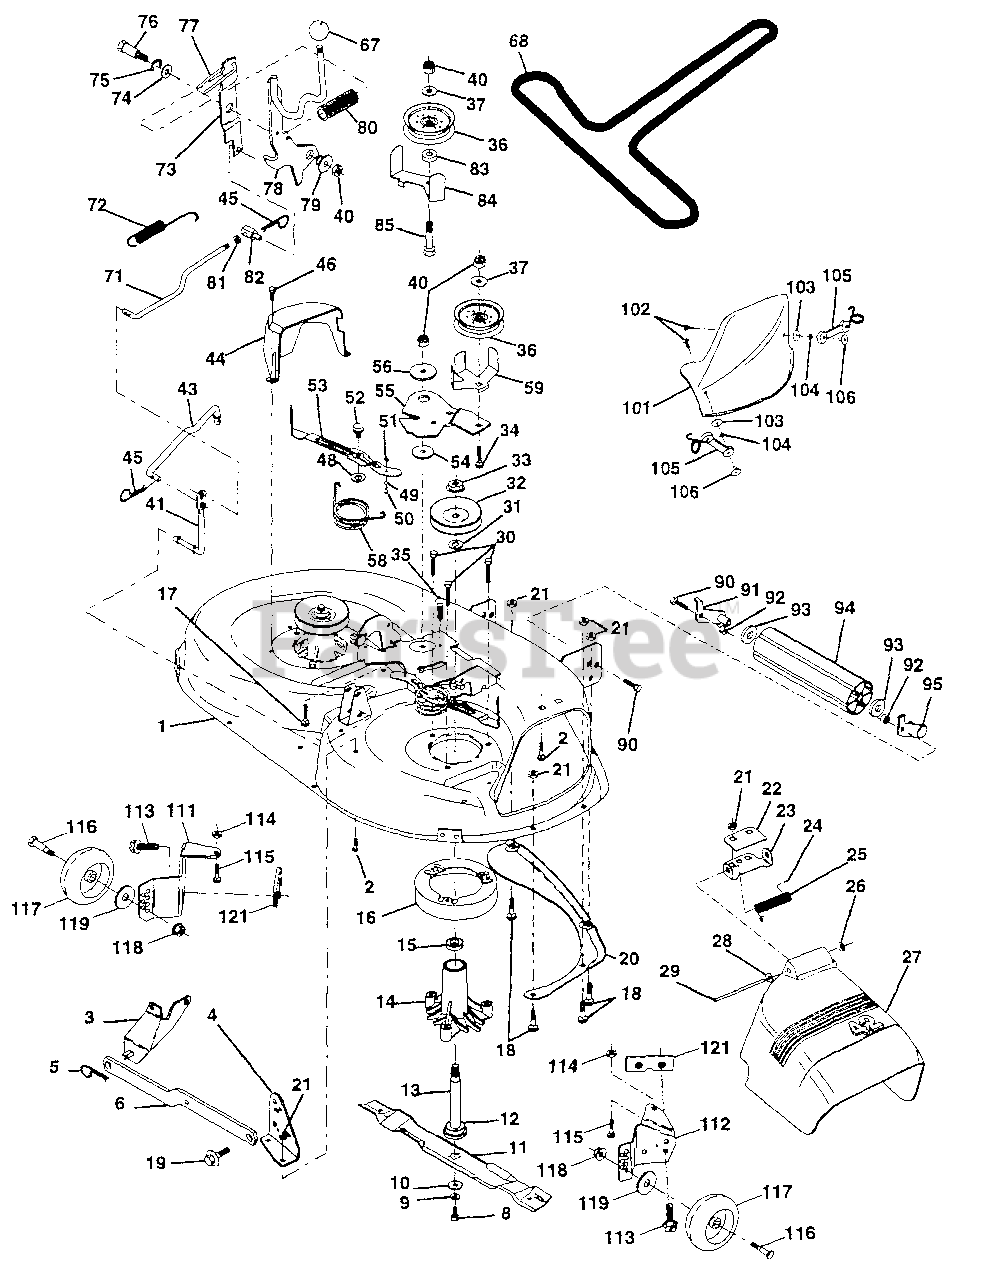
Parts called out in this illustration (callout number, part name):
1	Mower Housing Asm MWR 42" weldment T-Path
2	Bolt Rdhd Sqnk 5/16-18unc X3/4
3	Bracket Asm Fr Sway Bar 38/42
4	Bracket Asm Deck 42"sway Bar
5	Retainer Spring
6	Arm Suspension Rear
8	Bolt 3/8 - 24 X 1.25 Gr 8
9	Washer Lock Hvy 3/8
10	Washer Hard Blade Mower Vented
11	Blade Mower Mulching 42"
12	Bearing Ball #6024 (Mandrel)
13	Shaft Asm W/lower Bearing
14	Housing Mandrel Vented
15	Bearing Ball Mandrel
16	Stripper Mower Vented
17	Bolt Rdhd Sqnk 3/8-16 X 1-1/4
18	Bolt Rdhd Sqnk 5/16-18 X 5/8
19	Bolt Shoulder
20	Baffle Vortex 42
21	Nut Crownlock 5/16-18 UNC
22	Stiffener Bracket 42" deck
23	Bracket Deflector Mower 42"
24	Cap Sleeve 80x 112 Blk Mower
25	Spring Torsion Deflector 2 52
26	Nut Push Phos & Oil
27	Shield Deflector Mower 42" Blk
28	Washer 11/32 X 5/8 X 16 Ga
29	Rod Hinge 42" 6 75 Wlg
30	Screw Thdrol Hex Head Zinc Mwr
31	Washer Spacer Mower Vented
32	Pulley Mandrel 42"
33	Nut 9/16 Toplock Flng Oil Dip
34	Bolt Rdhd 3/8-16uncx1-3/4 Gr5
35	Fastner Christmas Tree
36	Pulley Idler Flat 3 060
37	Washer 13/32 X 13/16 X 16
40	Nut Crownlock 3/8-16 UNC
41	Rod Pivot W/nibs
43	Rod Clutch Secondary W/nibs
44	Guard Mandrel LH Black
45	Spring Retainer 1" Zinc/cad
46	Screw Hex Thd Cut 1/4-20x5/8 T
48	Washer Hardened Smaller
49	Roller Asm Cam Follower 42" deck
50	Bolt Shldr 10-24 Zinc Gr 5 42"
51	Nut Lock #10-24 Unc
52	Bolt Shoulder 5/16-18 Unc Blkz
53	Arm Asm Pad Brake
54	Washer Hardened
55	Arm Idler 42" mower LT/YT
56	Spacer Retainer Pm Mower
58	Spring Torsion Brakes
59	Guard TUV Idler
67	Knob Rd 1/2-13 Plstc Thds Blk
68	V-Belt Mower 42"
71	Rod Clutch Primary 38/42
72	Spring Return
73	Arm Clutch Secondary
74	Washer 25/32 X 1-5/8 X 16 Ga
75	Ring Klip #t5304-75
76	Bolt Shoulder 3/8-16 Unc 1 44
77	Keeper Spring 4 000
78	Arm Asm Clutch Primary
79	Bushing 747 Od X 794 Lg Brass
80	Spring Clutch Mower 2 750 Zinc
81	Nut Hex Jam 3/8-16
82	Trunnion Adj 94
83	Washer Sintered
84	Keeper Belt Idler Fixed
85	Bolt RDHD 3/8-16 x 2-1/4 Gr.5
90	Bolt Fin Hex 3/8-16 UNC x 1
91	Bracket Asm Noseroller LH
92	Nut Lock Hex W/Ins 3/8-16 Unc
93	Washer 17/32 x 7/8 x 16 Ga.
94	Roller Nose 38 & 42
95	Bracket Asm Noseroller RH
101	Cover Mulching 42" Black
102	Screw
103	Washer #10
104	Washer Lock #10
105	Latch Asm Bagger
106	Nut Weld
111	Bracket Wheel Gauge LH 42" Deck
112	Bracket Gauge Wheel RH 42" Deck
113	Screw Thdrol 5/16-18 X 3/4
114	Nut Keps 5/16-18 UNC
115	Bolt Carriage 5/16-UNC x 1/2
116	Bolt Shoulder
117	Wheel Gauge Donut
118	Nut Centerlock 3/8-16 UNC
119	Washer 3/8 x 7/8 x 14 Ga.
120	Washer 17/32 x 15/16 x 12 Ga.
121	Bracket Extruded Gauge Wheel
